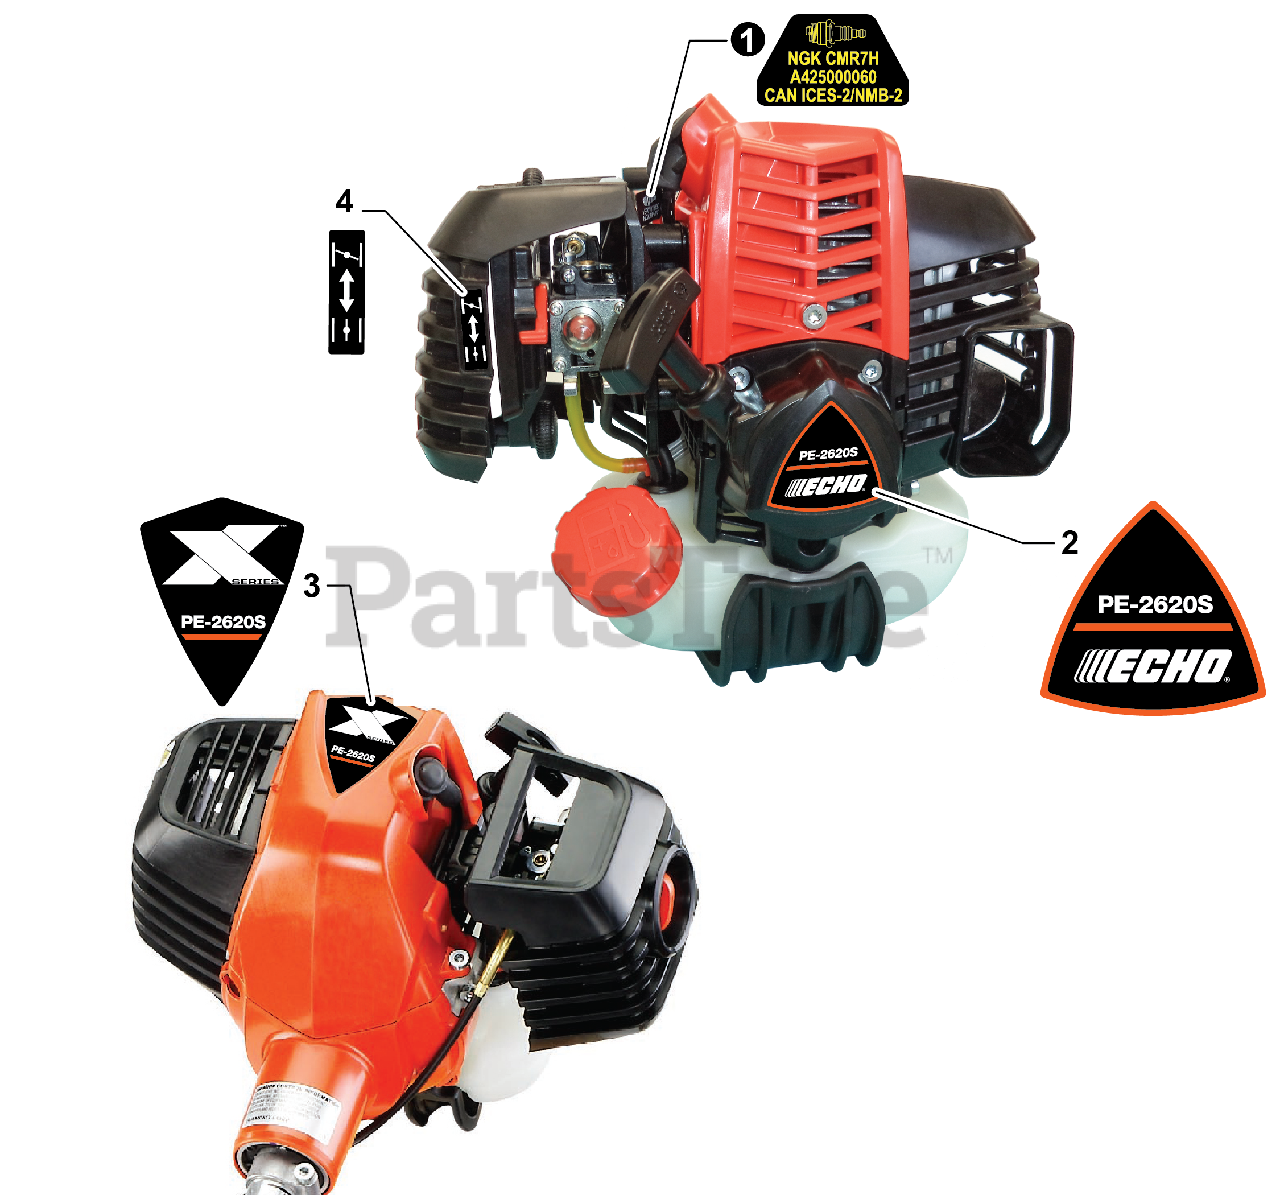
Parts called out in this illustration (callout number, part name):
1	LABEL, SPARK PLUG - CMR7H
2	LABEL, RECOIL STARTER - PE-2620S
3	LABEL - MODEL PE-2620S
4	LABEL, CHOKE
